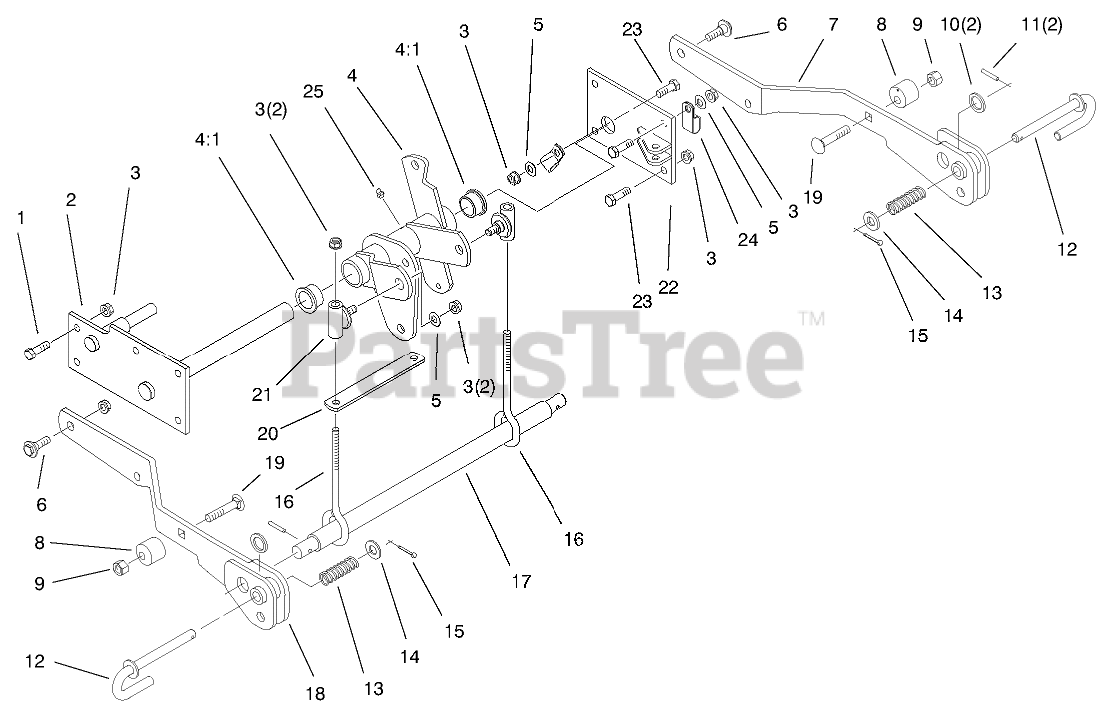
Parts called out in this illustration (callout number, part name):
1	SCREW-HH
2	SUPPORT-LIFT, DECK
3	NUT-LOCK, NI
4	BELLCRANK & BUSHING ASM
4:1	BUSHING-FLANGED
5	WASHER-FLAT
6	BOLT-SHOULDER
7	ARM-LIFT, LH
8	STOP-LIFT, ADJ.
9	NUT-LOCK, NI
10	WASHER-FLAT
11	PIN-ROLL
12	PIN - J
13	SPRING-COMPRESSION
14	WASHER-FLAT
15	PIN-COTTER
16	ROD - LIFT
17	BAR-LIFT
18	Arm-Lift, RH
19	SCREW-CARR
20	SPACER-STRAP
21	WA - LIFT SLEEVE
22	PLATE - LH SUPPORT
23	SCREW-HH
24	CLAMP-TUBE
25	FITTING-GREASE
